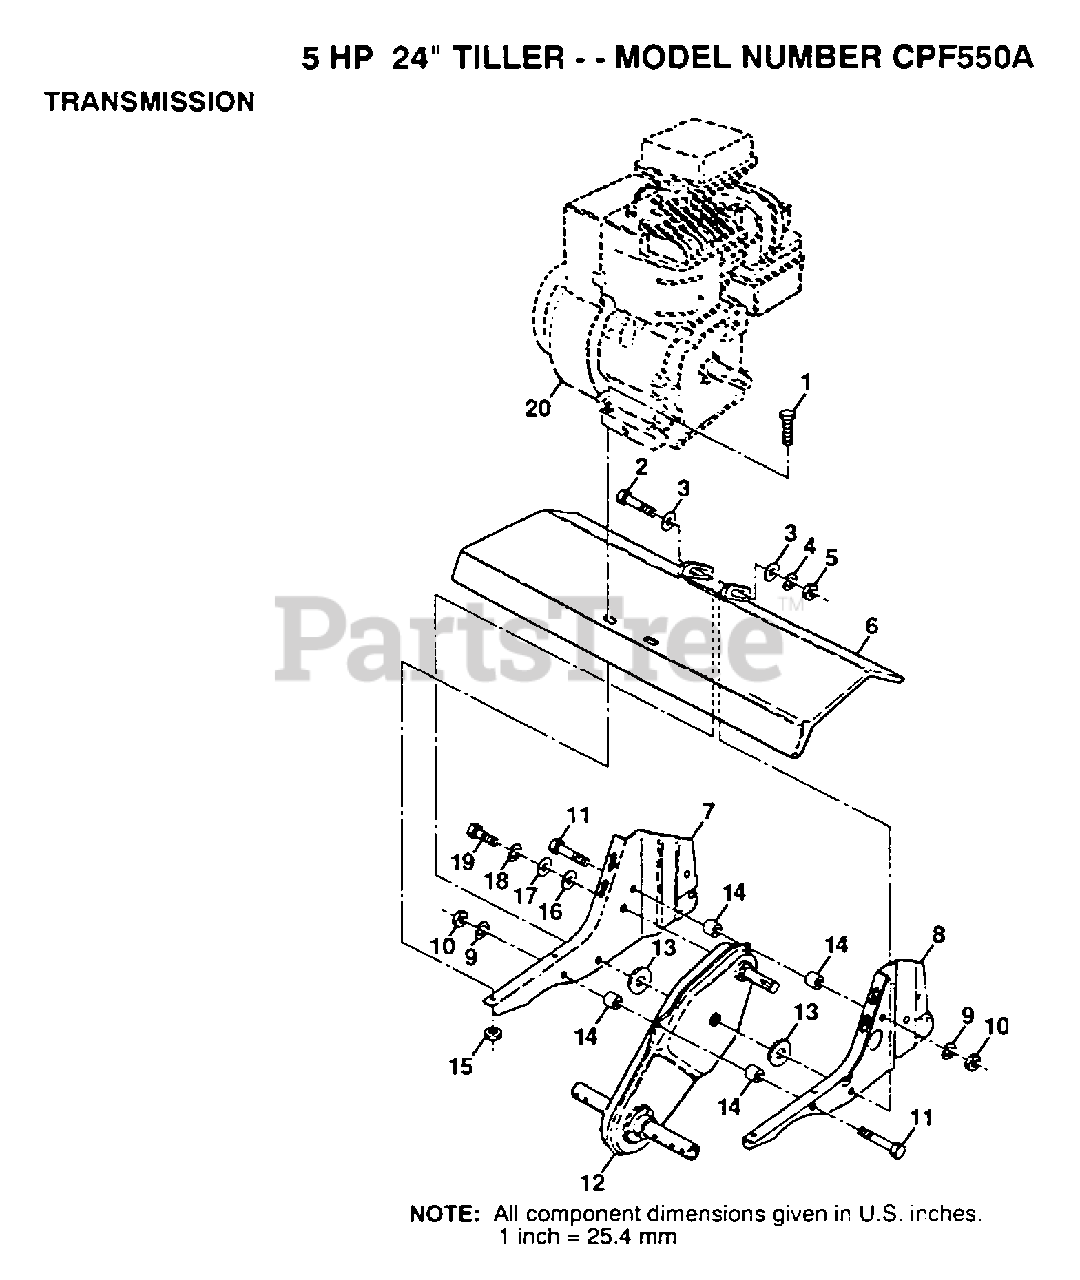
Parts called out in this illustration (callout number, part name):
1	BOLT.HEX.5/16-1.5
2	BOLT.3/8-24X3.75
3	WASHER
4	LOCKWASHER
5	GRIPCO NUT
8	BRACKET.ENG.LH.
9	LOCKWASHER
10	NUT.HEX.5/16-18
14	SPLIT SPACER RT
16	WASHER
17	WASHER
18	LOCKWASHER
19	BOLT
